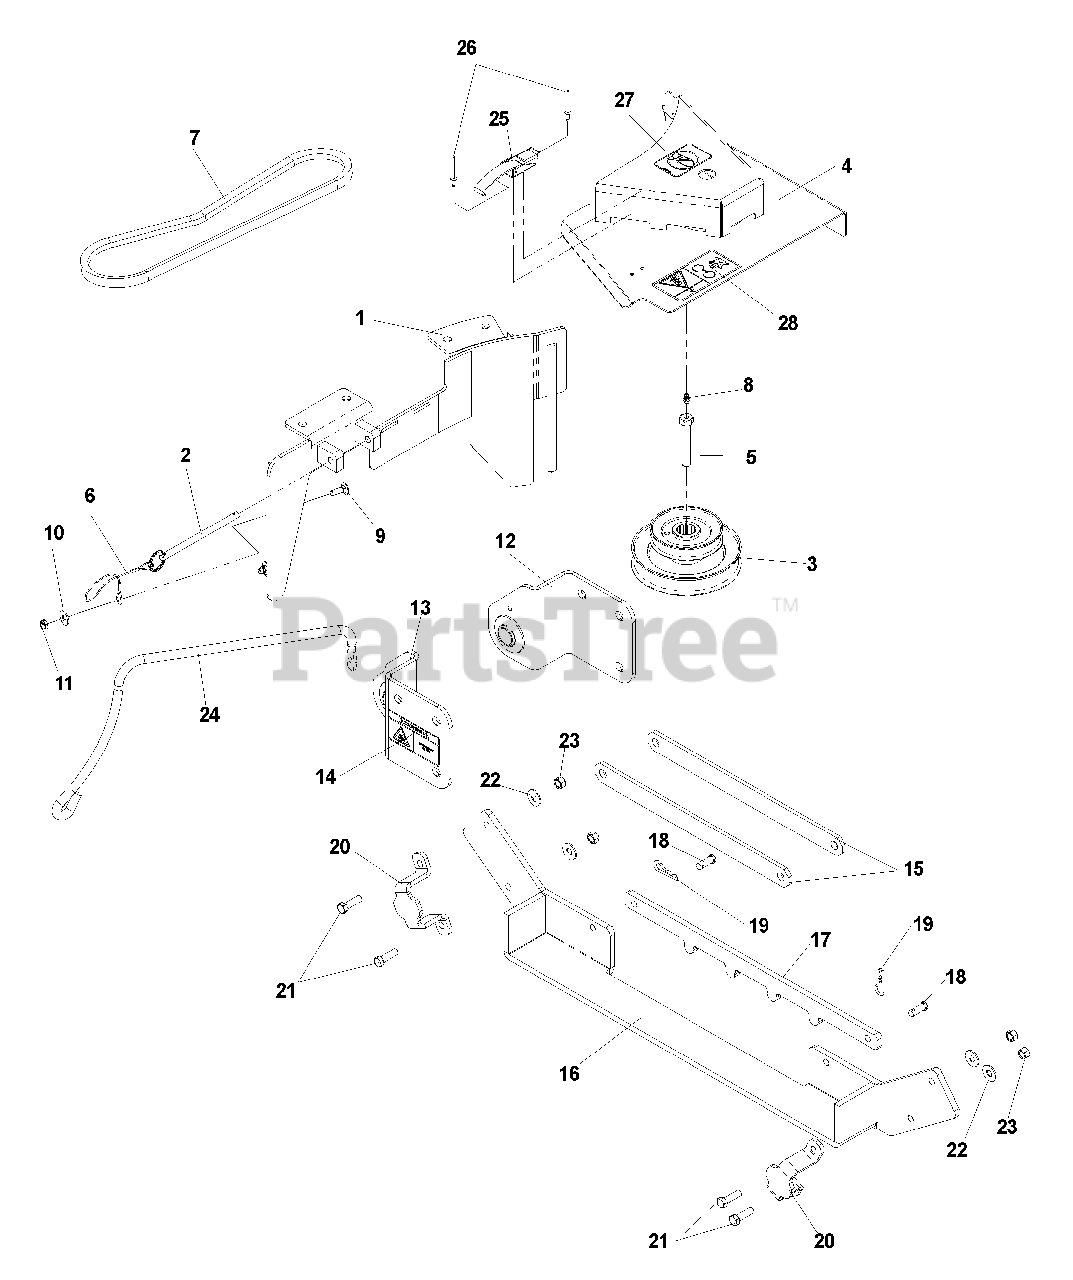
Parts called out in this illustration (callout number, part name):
1	BLOWER DECK PLATE, 52" DECK
1	BLOWER DECK PLATE,61" DECK
3	STACK PULLEY, 52" DECK
3	STACK PULLEY,61" DECK
4	BELT SHIELD, 52" DECK
4	BELT SHIELD,61" DECK
5	HCS, 7/16-20 X 2 1/2, GR8
7	BELT, 52" DECK
7	BELT, 61" DECK
8	ZERK
9	RHSNB, 1/4-20 X 3/4, GR2
10	WASHER, 1/4
11	NUT, 1/4-20, JAM, NYLOC
12	HITCH BRACKET, LEFT
13	HITCH BRACKET, RIGHT
14	DECAL, HOT SURFACE
16	WEIGHT BAR
17	HOLD DOWN, WEIGHT BAR
18	CLEVIS PIN
19	SPRING RETAINER
20	WEIGHT KEEPER
21	HCS, 3/8-16 X 1 1/4, GR5
22	WASHER, 3/8
23	NUT, 3/8-16, NYLOC
24	HOSE SUPPORT
25	DRAW LATCH
26	RIVET, BLIND, 5/32 DIA.
27	DECAL, NO STEP
28	DECAL, DANGER BELT DRIVES
